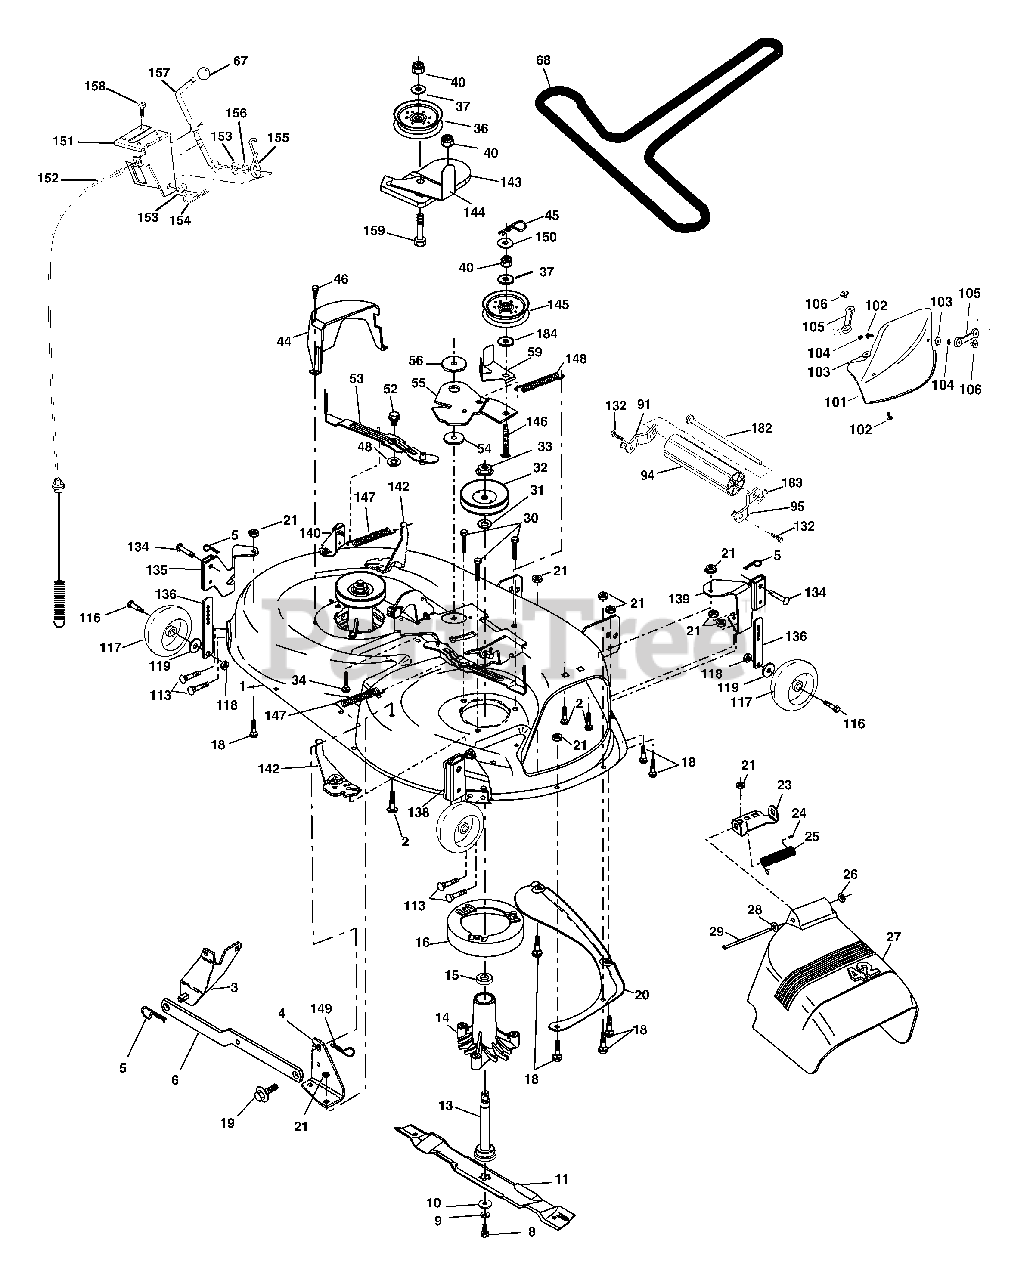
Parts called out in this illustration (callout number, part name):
1	Mower Deck Assembly, 42"
2	Bolt
3	Bracket Asm Fr. Sway Bar 3/42
4	Bracket Asm Deck 42" Sway Bar
5	Retainer Spring
6	Bar Sway Deck
8	Bolt 3/8-24 x 25 Grade 8 patched
9	Washer, Lock
10	Washer, Hardened
11	Blade, 42" Mulching Std
11	Blade, 42" Mulching Premium
11	Blade, 42" Hi-Lift
13	Shaft Assembly, Mandrel, Vented
14	Housing, Mandrel, Vented
15	Bearing, Ball, Mandrel
16	Stripper, Mandrel Deck
18	Bolt, Carriage 5/16-18 x 5/8
19	Bolt, Shoulder
20	Baffle, Vortex
21	Nut
23	Bracket, Deflector Mower 42"
24	Cap, Sleeve 80 x 112 Blk Mower
25	Spring, Torsion, Deflector 2 52
26	Nut, Push Phos & Oil
27	Shield, Deflector 42" Blk
28	Washer 11/32 x 5/8 x 16 Gauge
29	Rod, Hinge 42" 6 75 W/G
30	Screw Thdrol Washer Head
31	Washer, Spacer Mower Vented
32	Pulley, Mandrel
33	Nut, Toplock 9/16 Flange
34	Bolt
36	Pulley, Idler, Flat
37	Washer 13/32 x 13/16 x 16 Gauge
40	Nut
44	Guard, Mandrel, LH
45	Retainer
46	Screw, Thdrol 1/4-20 x 5/8 T
48	Washer, Hardened
52	Bolt, Shoulder 5/16-18 UNC
53	Arm Assembly, Pad, Brake
54	Washer, Hardened
55	Arm, Idler
56	Spacer, Retainer
59	Guard TUV Idler
67	Knob
68	V-Belt, 42" Mower
91	Bracket Asm. Noseroller LH
94	Roller, Nose
95	Bracket Asm. Noseroller RH
101	Mulcher Cover
102	Screw
103	Washer, Flat
104	Washer, Lock
105	Latch Assembly
106	Nut, Weld
113	Screw 5/16-18 x 3/4
116	Bolt, Shoulder
117	Wheel, Gauge
118	Nut Centerlock 3/8-16
119	Washer 3/8 x 7/8 x 14 Ga.
132	Screw 3/8-16 x .75
134	Pin Head Rivet
135	Bracket Asm. Whl. Ga. Rear LH
136	Bar Adjusting Gauge Wheel
138	Bracket Asm. Whl. Ga. Rear RH
139	Bracket Asm. Whl. Ga. Front RH
140	Bracket Asm. Whl. Ga. Front LH
142	Arm Spring Brake Mower
143	Bracket Arm Idler 42"
144	Keeper Belt 42" Clutch Cable
145	Pulley Idler Flat
146	Bolt Carriage Idler
147	Spring Extension
148	Spring Return Idler
149	Retainer Spring Yellow
150	Washer 9/32 x 3/4 x 16 Ga.
151	Bracket Clutch Cable
152	Clutch Cable 42"
153	Washer Flat 3/8" Type B
154	Spring Retainer
155	Spring Retention LVR CLTCH CAB
156	Spacer Clutch Cable
157	Rod Clutch Cable 3/8"
158	Screw Hex Thd Cut 1/4-20 x 5/8
159	Bolt Rdhd Sqn 3/8-16 UNC x 1-3/4
182	Rod Roller Nose
183	Retainer Spring
